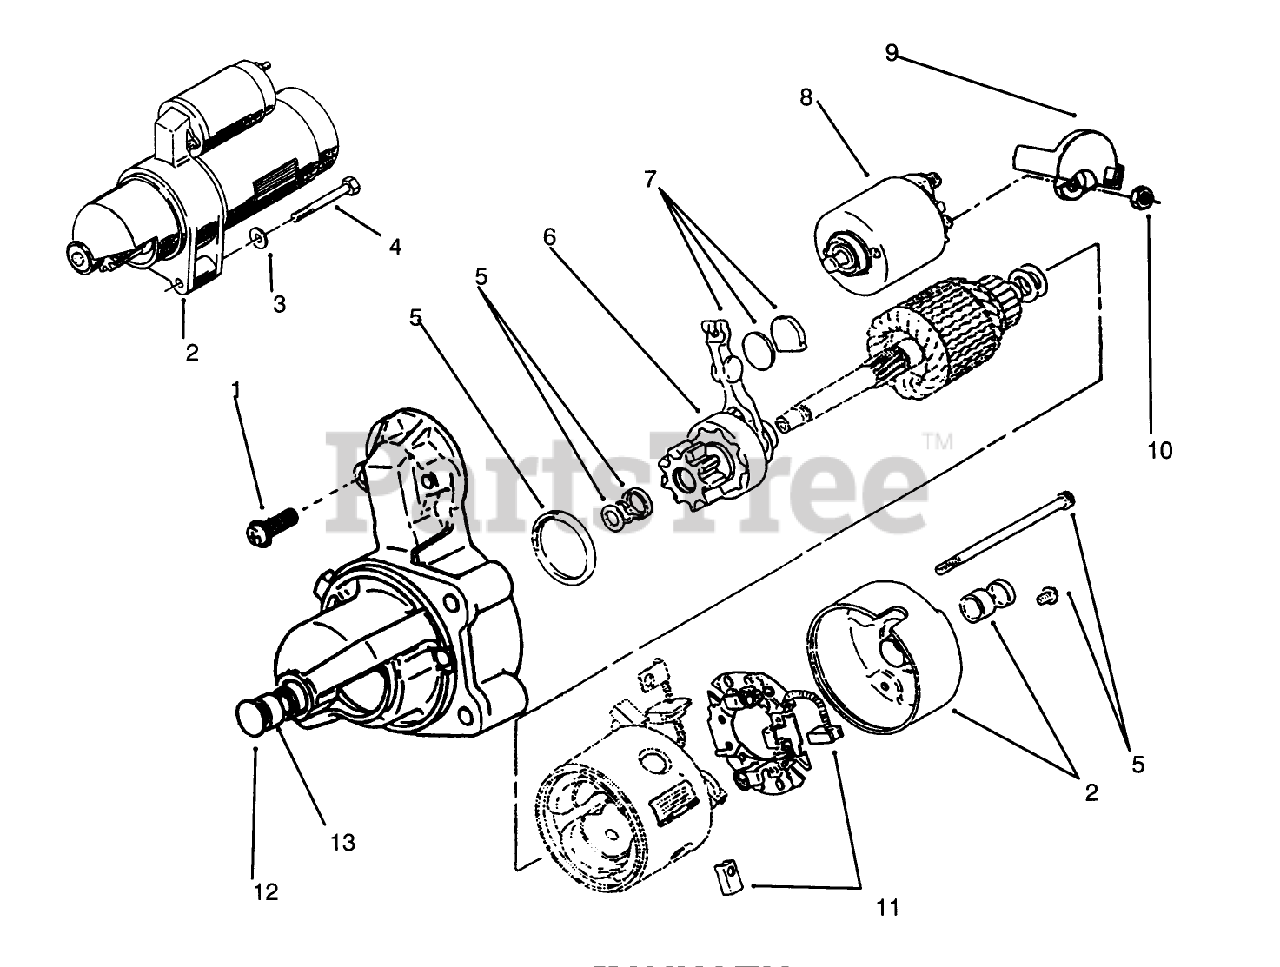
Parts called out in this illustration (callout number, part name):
3	WASHER
12	BUSHING
13	KIT-MTG BRKT
